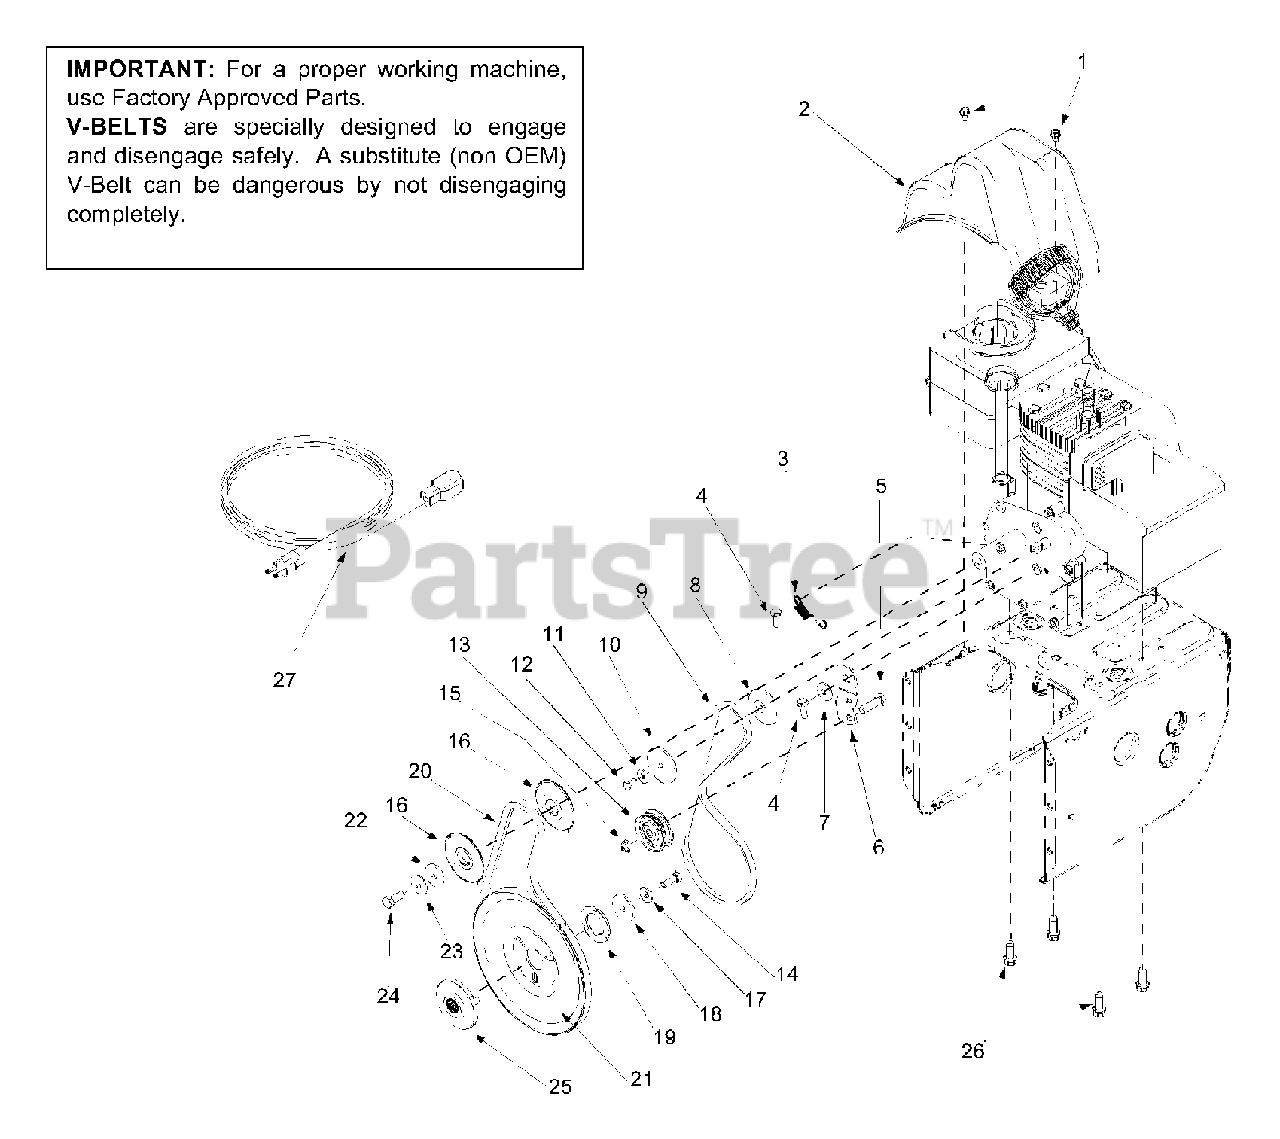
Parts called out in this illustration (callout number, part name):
1	Hex Washer Screw 1/4-20 x.625
2	Belt Cover
3	Extension Spring
4	Hex Screw 5/16-24 x .75
5	Hex Cap Screw 3/8-16 x 1.25
8	Pulley Half
9	V-Belt
10	Pulley Half
11	Bell Washer
12	Hex Cap Screw 1/4-28 x .50
13	Flat Idler
14	Lock Cap Screw 5/16-24
15	Lock Jam Nut 3/8-16
16	Pulley Half
17	Bell Washer
18	Flat Washer
19	Washer
20	Belt
21	Auger Pulley
22	Flat Washer
23	Bell Washer
24	Hex Cap Screw 3/8-24
25	Pulley
26	Hex Washer Screw 3/8-16 x 1.0
27	Extension Cord
